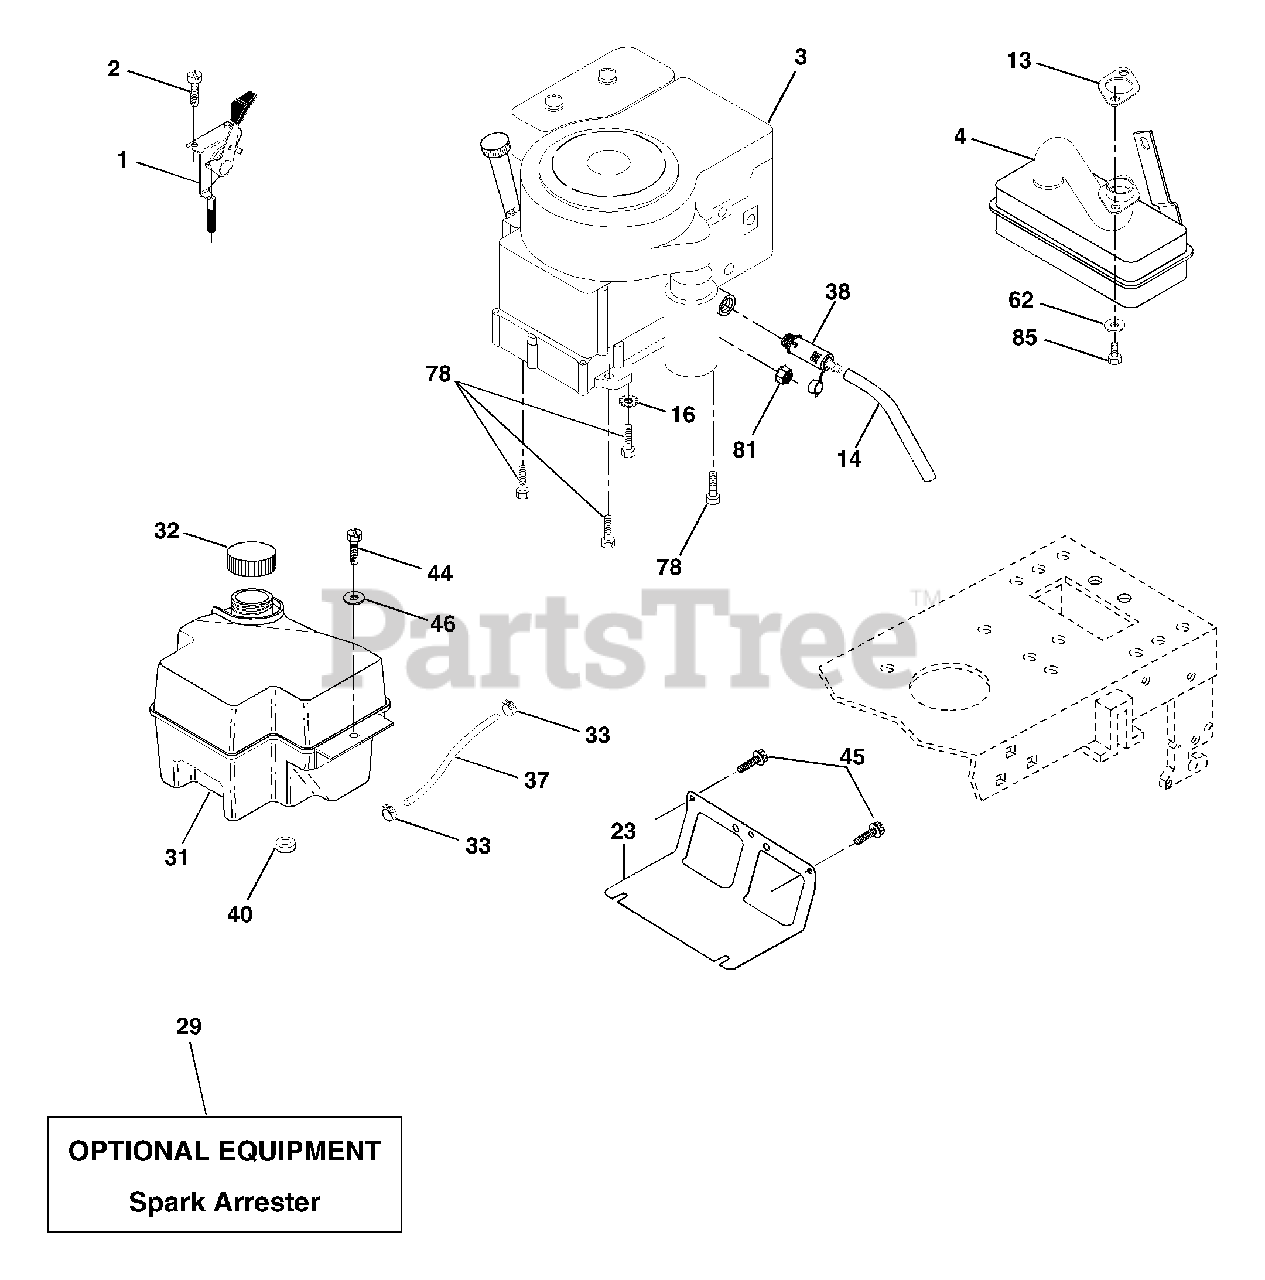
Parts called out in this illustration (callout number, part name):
1	Control Throt/Ch
2	Screw Hex Thd Cut 1/4-20x5/8 T
4	Muffler Tec 13.5/17 Lt
13	Gasket
14	Tube Drain Oil Easy
16	Washer Lock Ext Tooth 3/8
23	Shield Browning
29	Arrestor Spark
31	Tank Fuel 2.00 Fr
32	Cap Asm Fuel w/ Gauge
33	Clamp Hose Blk
37	Line Fuel 20"
38	Plug Drain Oil Easy
40	Bushing Snap Nyl Blk Fuel Line
44	Screw Hexwsh Thdrol 1/4-20x3/4
45	Screw 5/16-18 x 3/4
46	Washer 9/32 X 7/8 X 16ga
62	Washer Lock Hvy Hlcl Spr 5/16
78	Screw 3/8-16x1-1/4
81	Nut Flange 1/4-20 Starter Nut
85	Bolt Hex Hd Phillips
